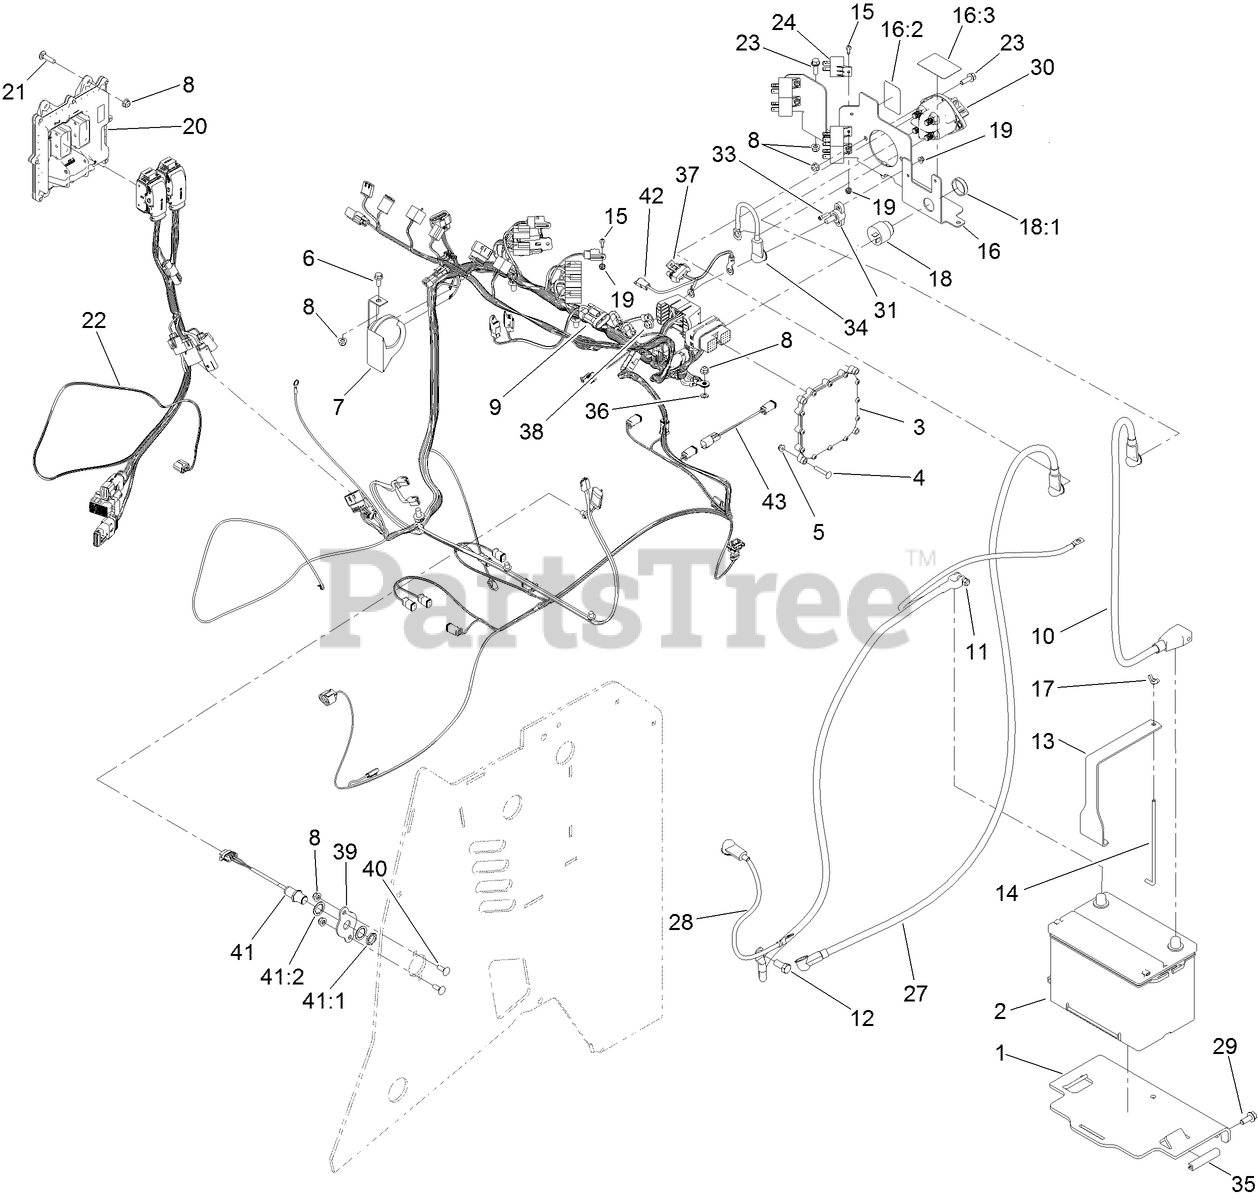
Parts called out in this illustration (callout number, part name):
1	BRACKET-BATTERY
2	BATTERY
3	CONTROLLER
4	SCREW-CARR
5	NUT-HF
6	SCREW-HHF
7	Horn And Bracket Assembly (Inc. Ref.# 44 45)
8	NUT-HF, NI
9	HARNESS-WIRE
10	CABLE-BATTERY, POSITIVE
11	CABLE-BATTERY, NEGATIVE
12	SCREW-HH
13	PLATE-HOLD, BATTERY
14	ROD-HOLD DOWN, BATTERY
15	SCREW-HWH
16	BRACKET-COMPONENTS, ELECTRICAL
16:2	DECAL-BATTERY POWER
16:3	DECAL-FUSES
17	NUT-WING
18	AUDIO ALARM ASM
19	NUT-HF
20	ECU-ENGINE
21	SCREW-CARR
22	HARNESS-ENGINE
23	SCREW-HHF
24	RELAY
27	CABLE-BATTERY, POSITIVE
28	CABLE-BATTERY, POSITIVE
29	SCREW-HHF
30	SWITCH-DISCONNECT
31	BLOCK-JUNCTION
33	SCREW-HSH
34	CABLE-BATTERY, POSITIVE
36	WASHER-LOCK
37	HARNESS-WIRE, FUSIBLE LINK
38	NUT-HF, NI
39	PLATE-MOUNT, SENSOR
40	SCREW-CARR
41	PROXIMITY SWITCH ASM
41:1	NUT-HEX
41:2	WASHER-LOCK, INTERNAL TOOTH
42	HARNESS-WIRE, FUSIBLE LINK
43	HARNESS-JUMPER
